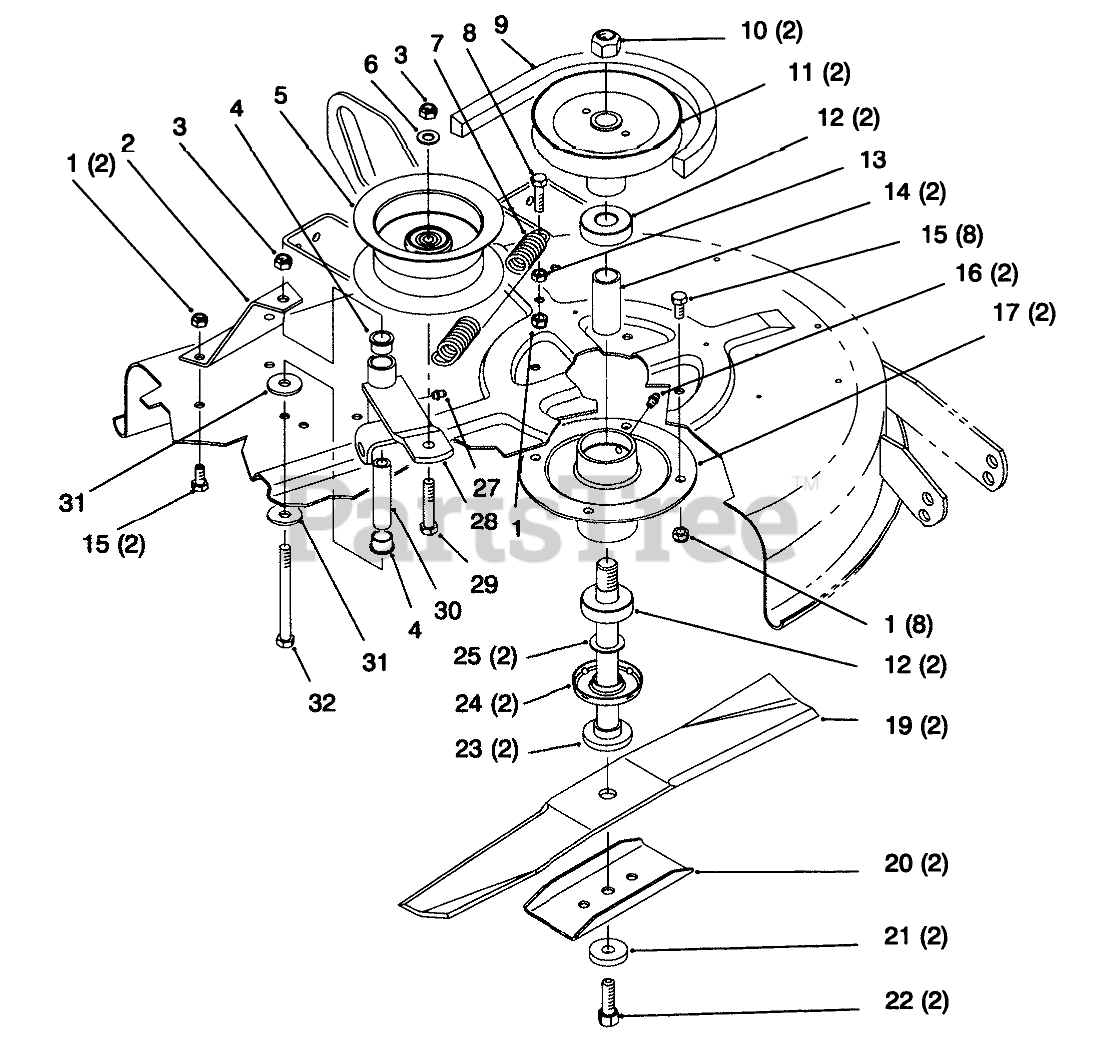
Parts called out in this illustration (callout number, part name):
1	NUT-LOCK, NI
3	NUT-LOCK, NI
4	BUSHING
5	PULLEY-IDLER
6	WASHER-FLAT
7	SPRING-EXTENSION
8	SCREW-HH
9	V-BELT
10	Nut-Hex
11	PULLEY
12	BEARING-BALL
13	NUT-HEX
14	SPACER
15	SCREW-HH
16	ZERK FITTING
17	HOUSING-SPINDLE (BLACK)
19	Blade
19	BLADE KIT
20	STIFFENER-BLADE
21	WASHER
21	WASHER-BELLEVILLE
22	SCREW-HH
23	SHAFT-SPINDLE
24	SHIELD-BEARING
25	SPACER-HARDNED
27	FITTING-GREASE
28	WLDMT-IDLER ARM (BLACK)
29	SCREW-HH
30	SPACER
31	WASHER
32	SCREW-HH
